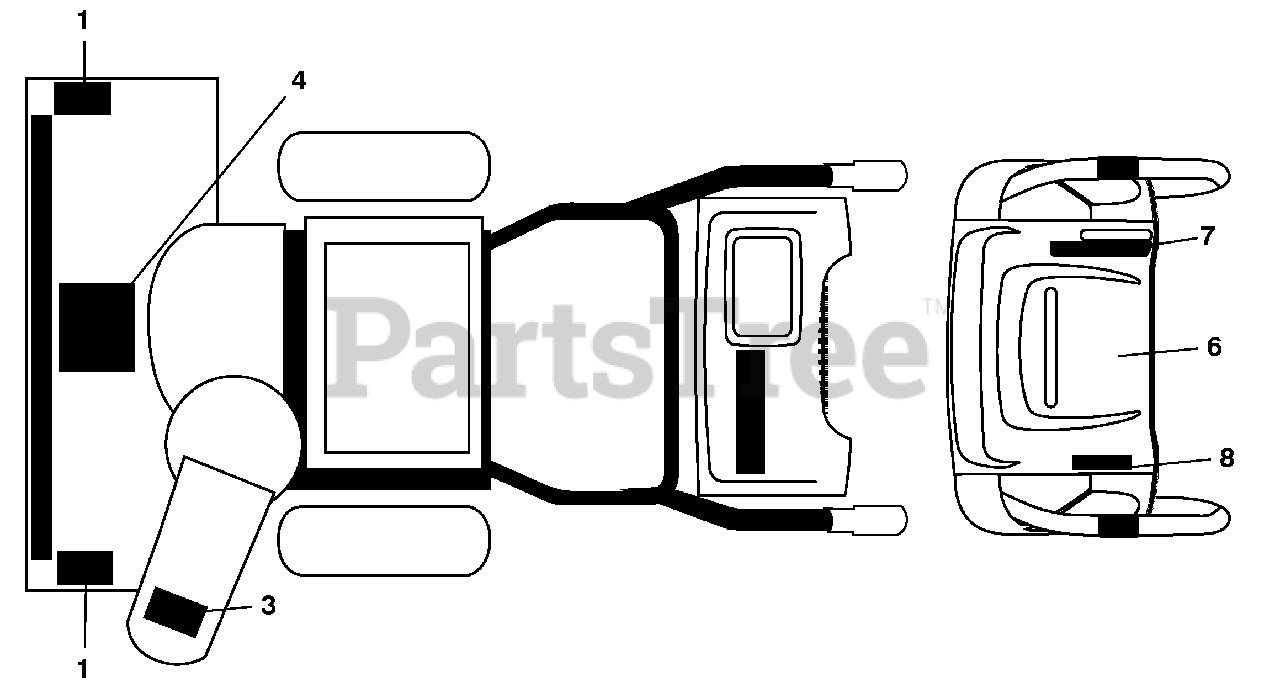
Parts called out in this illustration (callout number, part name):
1	DECAL, DANGER
3	DECAL, DANGER, DEFLECTOR
4	DECAL, DANGER
6	DECAL, INSTRUCTION
7	DECAL, CONSOLE, RH, SPEED
8	DECAL, CONSOLE, LH, SPEED
8	OWNER'S MANUAL, ENGLISH
8	OWNER'S MANUAL, FRENCH
